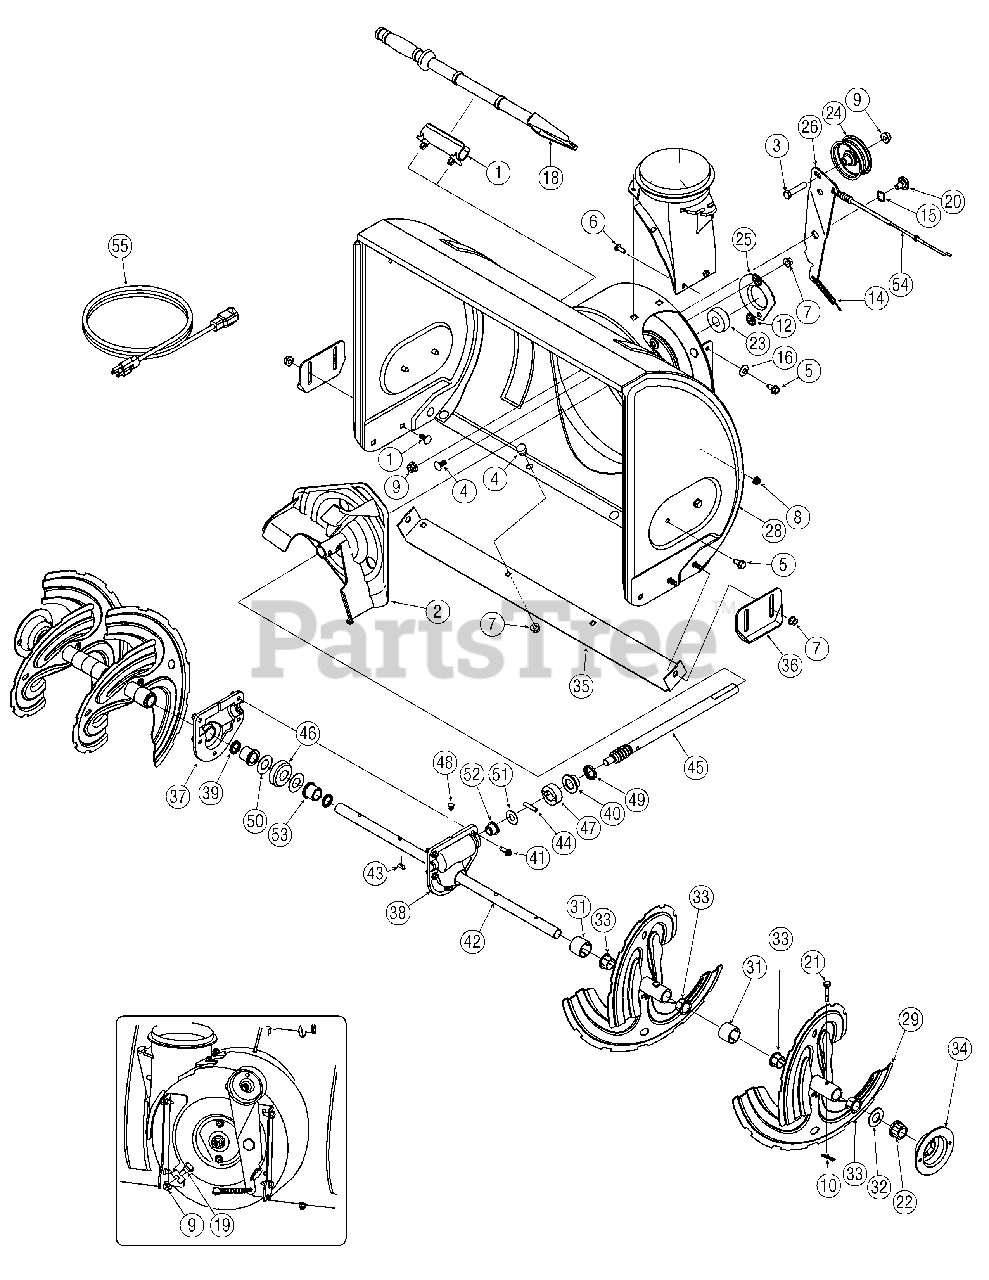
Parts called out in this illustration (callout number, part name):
1	Snow Removal Tool Mount
3	Hex Screw, 3/8-16, 1.75, Gr5
4	Bolt, Carriage, 5/16-18, .750 Gr1
5	Screw, 5/16-18, 0.625
6	Screw, Carriage, 1/4-20, .750, Gr5
7	Nut, Flange Lock, 5/16-18, Nylon
8	Nut, Flange Lock, 1/4-20, Nylon
9	Nut, Flange Lock, 3/8-16, Nylon
10	Cotter Pin, Bow-tie
11	Cable, Tie, 3/16 x .05 x 7.4
12	Nut, Push-on, .25 Dia
13	Chute, Adapter 5" Dia
14	Spring, Extension, .38 OD x 3.6
15	Washer, Wave, .625 x .885 x .015
16	Washer, Bell, .340 x .872 x .060
17	Washer, Flat, .25 x .630 x .0515
18	Snow Removal Tool
19	Screw, Shoulder, .498 x .34, 3/8-16
20	Screw, Shoulder, .625 x .17, , 3/8-16
21	Shear Pin, .25 x 1.50
22	Bearing, Hex Flange x .75 ID
23	Bearing, Ball, .75 ID x 1.85 OD
24	Flat Pulley, Idler, 2.75 OD
25	Housing, Bearing, 1.85 ID
27	Gearbox Assembly, Auger, 22"
27	Gearbox Assembly, Auger, 24"
27	Gearbox Assembly, Auger, 26"
27	Gearbox Assembly, Auger, 28"
31	Spacer, 1.25 OD x .75 ID
32	Washer, Flat, .76 x 1.49 x .06
33	Bushing, Flange, .80 ID x .91 OD
37	Housing, Auger, RH Reduced
38	Housing, Auger, LH Reduced
39	Seal, Oil, .750 ID
40	Bearing, Flange, .75 x 1.0 x .59
41	Screw, Self-tapping, 1/4-20, 0.750
42	Axle, Auger, 22"
42	Axle, Auger, 24"
42	Axle, Auger, 26"
42	Axle, Auger, 28"
43	Key, Hi-pro 3/16 x 5/8
44	Pin, Dowel, .25 OD x 1.2
45	Shaft, Worm .75 OD
46	Gear, Worm 20T
47	Collar, Thrust
48	Plug, 1/4 x .437
49	Seal, Oil, .75 x 1 x .131
50	Washer, Flat, .760 ID x 1.
51	Washer, Flat, .51 x 1.12
52	Bearing, Flange, .75 x 1.0 x .925
53	Bearing, Flange, .75 x 1.00 .975
54	Clutch Cable, Auger, 47.23"
55	Extention Cord, 110V
